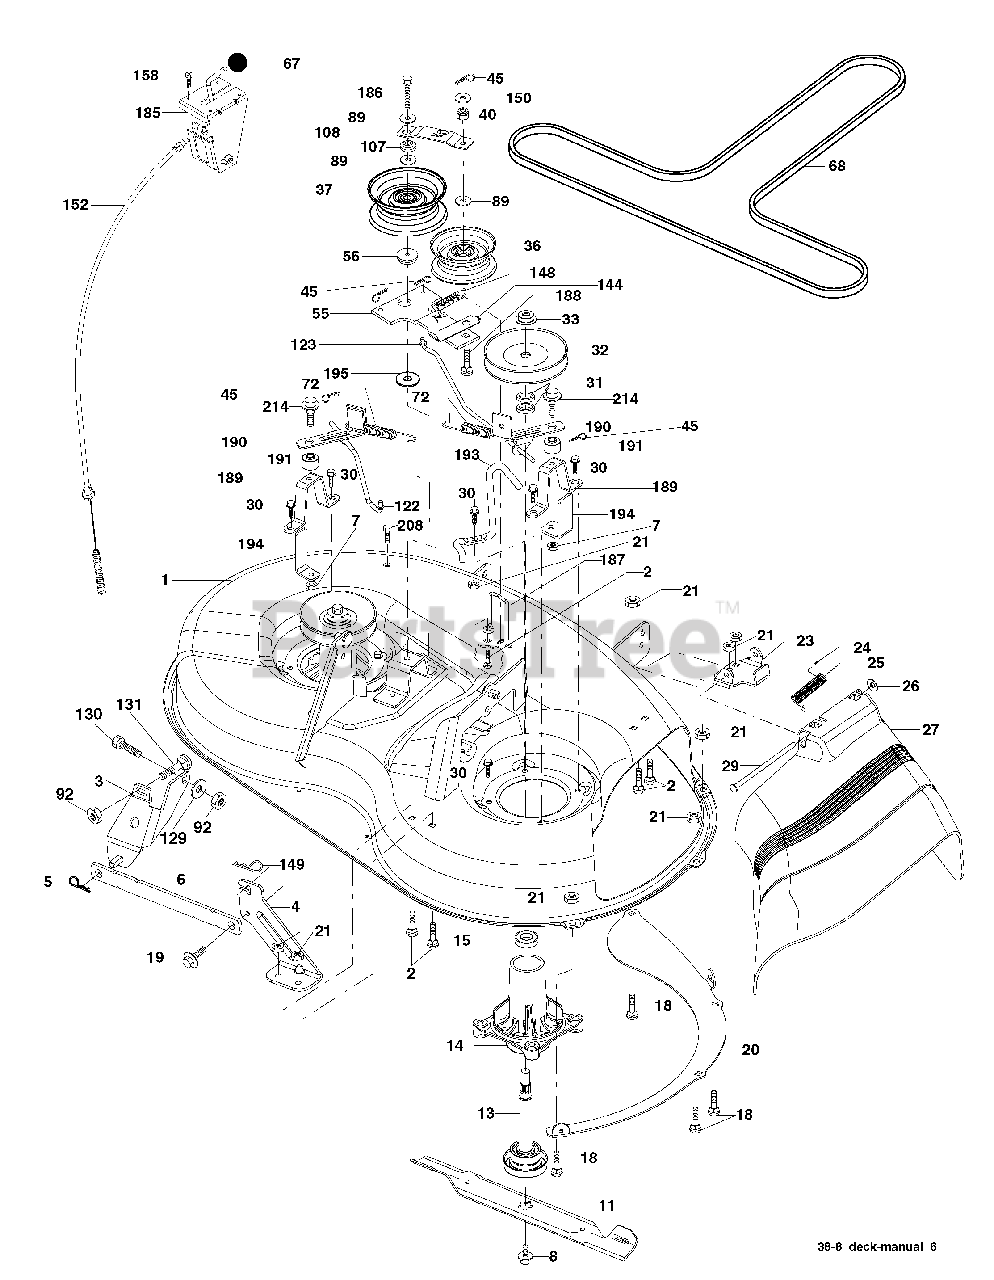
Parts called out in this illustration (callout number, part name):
1	Mower Housing Assembly
2	Bolt Carriage 5/16-18 x 3/4
3	Bracket Asm Fr. Sway Bar
4	Bracket Deck Sway Bar 38"/42"
5	Retainer Spring
6	Bar Sway Deck
7	Nut Lock Hex w/Insert 5/16-18 unc
8	Bolt 3/8-24 x 1.25 Gr. 8
11	Blade Mower
13	Shaft Assembly, Mandrel, Vented
14	Housing, Mandrel, Vented
15	Bearing, Ball, Mandrel
18	Blade Rdhd Sqnk 5/16-18 x 5/8
19	Bolt, Shoulder
20	Baffle Vortex Front
21	Nut
23	Bracket, Mower Deflector
24	Cap, Sleeve
25	Spring, Torsion, Deflector
26	Nut, Push
27	Shield, Deflector
29	Rod, Hinge
30	Screw Thdrol.
31	Washer, Spacer
32	Pulley, Mandrel
33	Nut, Toplock
36	Pulley, Idler, Flat
37	Pulley, Idler, Flat
40	Nut, Crownlock 3/8-16 unc
45	Retainer
55	Idler Arm Assembly
56	Spacer, Retainer
67	Knob
68	V-Belt
72	Spring Brake Return
89	Washer 13/32 x 13/16 x 11 Ga.
92	Nut Lock 3/8-16
107	Spacer Retainer
108	Stiffener, Idler Arm
122	Link, Brake LH
123	Link, Brake RH
129	Washer 3/8
130	Bolt Hex 3/8-16 x 1 Gr. 5
131	Bolt Carr 3/8-16 x 1
144	Keeper Belt Idler Tension
148	Spring Return Idler
149	Retainer Spring Yellow
150	Washer 9/32 x 3/4 x 10 Ga.
152	Clutch Cable 38"
158	Screw Hex Thd Cut 1/4-20 x 1/2
185	Head Asm Cable Clutch
186	Screw Hex Wsh Thdrol 3/8-16 x 2-3/4
187	Keeper Belt M Shape
188	Bolt Carriage Idler
189	Brake Stand
190	Brake Arm
191	Brake Spacer
193	Keeper Belt RH Mandrel
194	Brake Guard
195	Washer 13/32 x 2 x 10 Ga.
208	Screw Thdrol 3/8-16 x 1/2
214	Bolt/Washer Asm. 5/16-18
214	Mandrel Assembly
214	Brake Assembly
214	Replacement Mower, Complete
